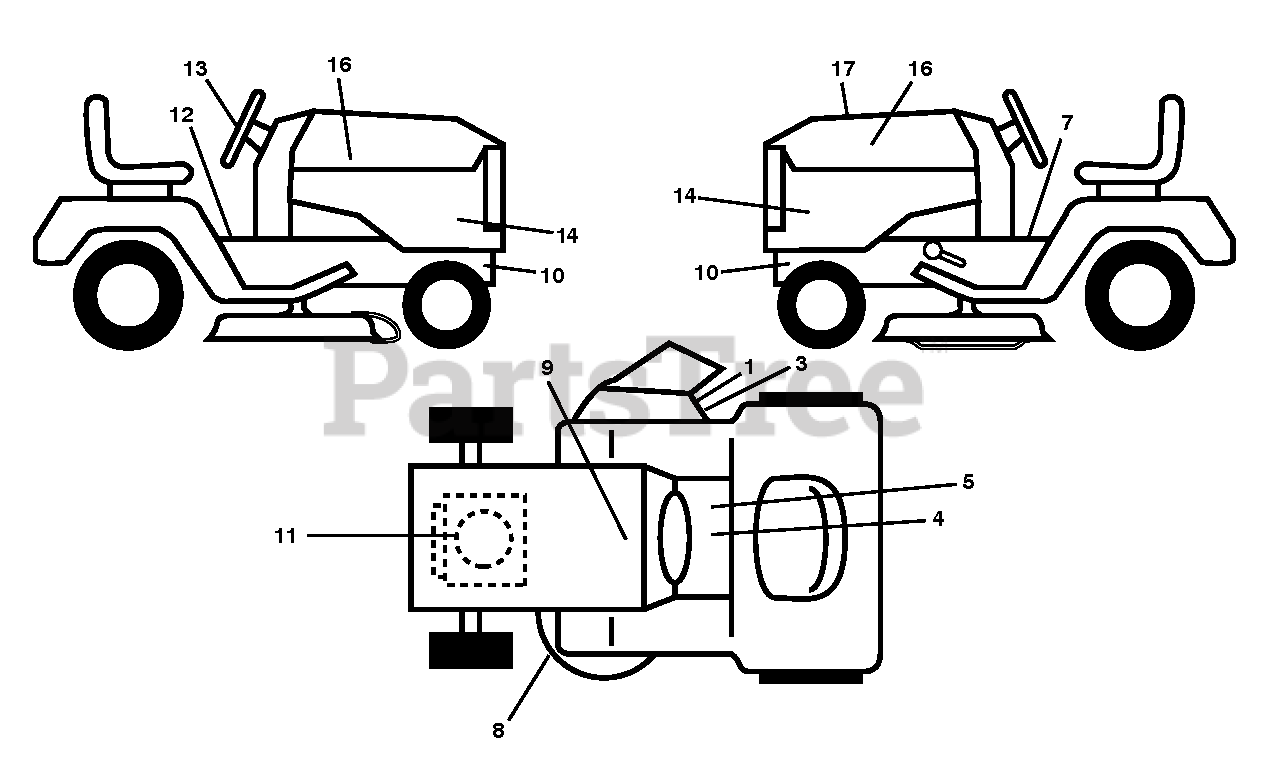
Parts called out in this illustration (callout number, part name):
1	DECAL.CUTFINGER.CE.02
3	DECAL.DFLCTR.WARNNG.CTFNGR.SYM
4	DECAL PARK BRAKE
5	DECAL.READ.OWN.MAN.SYMBOL.LT
7	DECAL
8	DECAL.V-BELT.SCH.42/46"MEC/ELE
9	DECAL BTRY SYMBOLS
11	DECAL.ENGINE.WARNING
12	DECAL
13	DECAL.WHEEL.STRG.LGN.H
16	DECAL.HOOD.NAMELOGO.HUSQ
